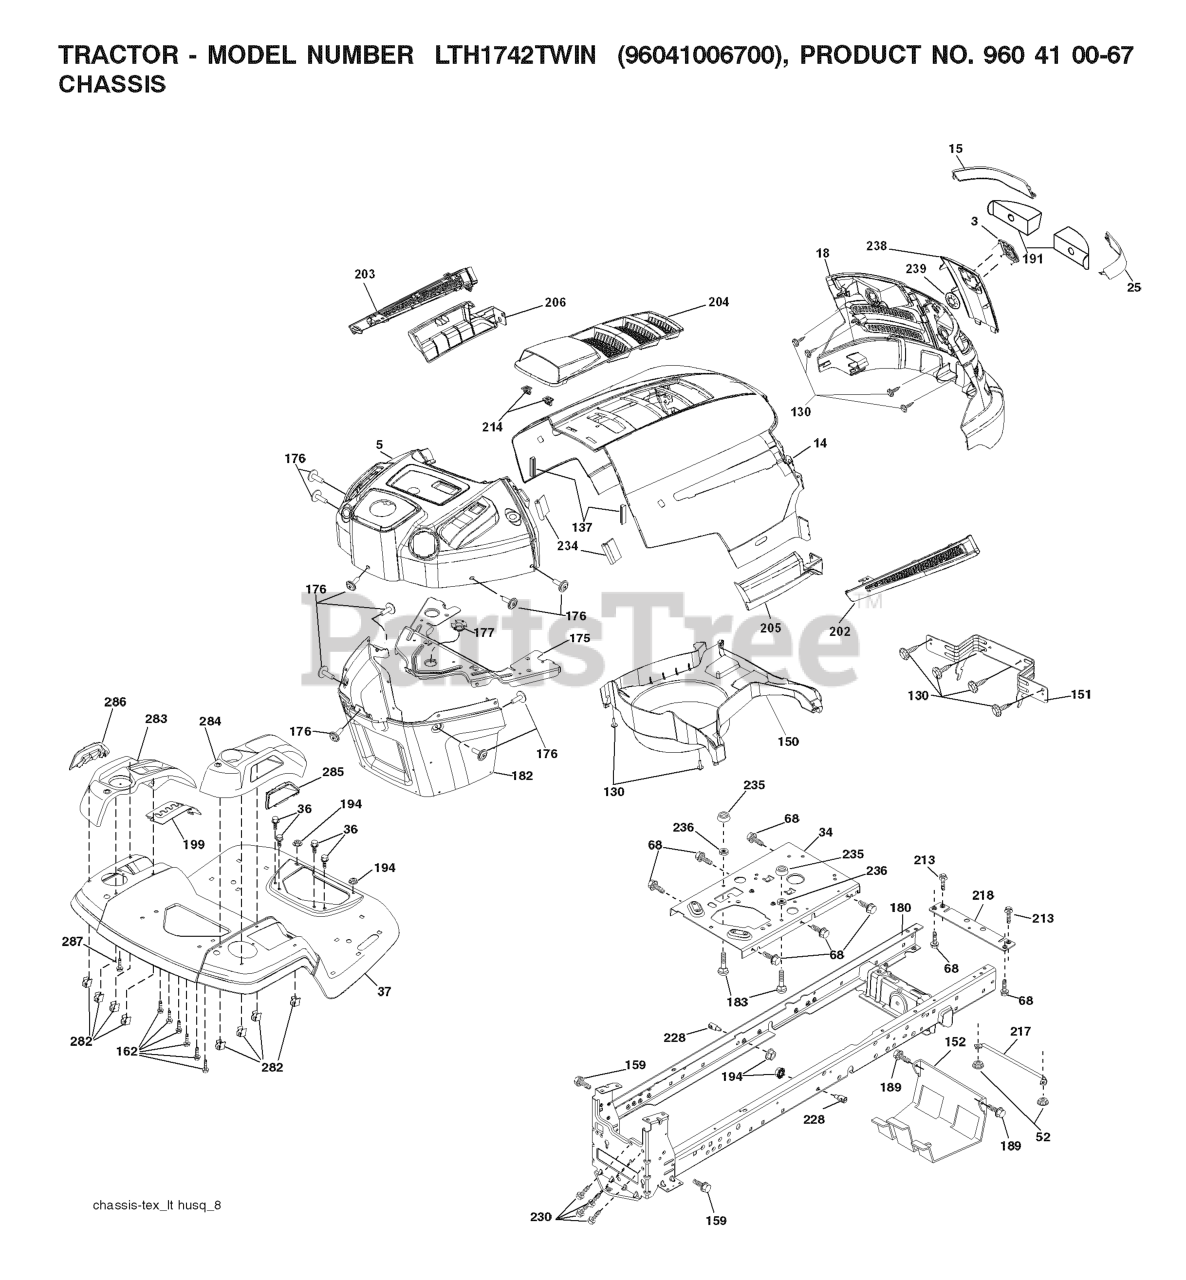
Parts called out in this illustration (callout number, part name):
3	RP LOGO
14	HOOD
15	LENS.HUSQVARNA LT.LH
18	RP GRILLE/LENS ASM.
25	LENS.HUSQVARNA LT.RH
34	PLATE.ENGINE.WELDED.CHASSIS
36	SCREW 5/16"
37	RP FENDER.TLT.FS.W/CPH.422
52	LOCKNUT
68	Screw 5/16-18 x 1/2 Hex, Self Tapping 5/16-18 x 1/2
130	SCREW.#10 X 0.750.BOS
137	BUMPER DASH
151	BRACKET PIVOT
152	SHIELD.BROWNING.W/TEX
159	SCREW, 3/8-16X3/4
162	SCREW.HI-LO.CONSOLE
175	CROSSMEMBER
176	SCREW.#10-24X5/8.RN.QU
177	BUSHING STEERING
180	CHASSIS
182	DASH LOWER
183	BOLT.5/16-18X1-1/4 FULL.THREAD
189	SCREW
191	INSERT REFLECTIVE
194	NUT LOCK HEX FLANGE 5/16-18
199	PLATE.DECK.LIFT.HUSQ.LT
202	VENT SIDE HOOD RH
203	VENT SIDE HOOD LH
204	VENT TOP HOOD
205	SKIRT SIDE RH
206	SKIRT SIDE LH
213	BOLT
214	CLIP.RETAINER.TINNER.
217	ROD.PIVOT.HOOD
218	X-PIECE.HOOD.STOP.NON/
228	STUD.FASTNER.W/ANTI-ROTATE
230	SHOULDER BOLT 5/16-18TT
234	BUMPER.HOOD.TEX.HUSQVARNA
235	SPACER FENDER
236	NUT.CENTERLOCK.5/16-
238	TRIM
282	CLIP.RETAINER.CONSOLE.LT.HUSQ
283	CONSOLE.DECK.LIFT.HUSQ.N/FR.GR
284	CONSOLE.CNTRL.
285	CONSOLE INSERT RH
286	CONSOLE.INSRT.LH.HUSQ.LT.BLACK
287	SCREW 1/4X20
